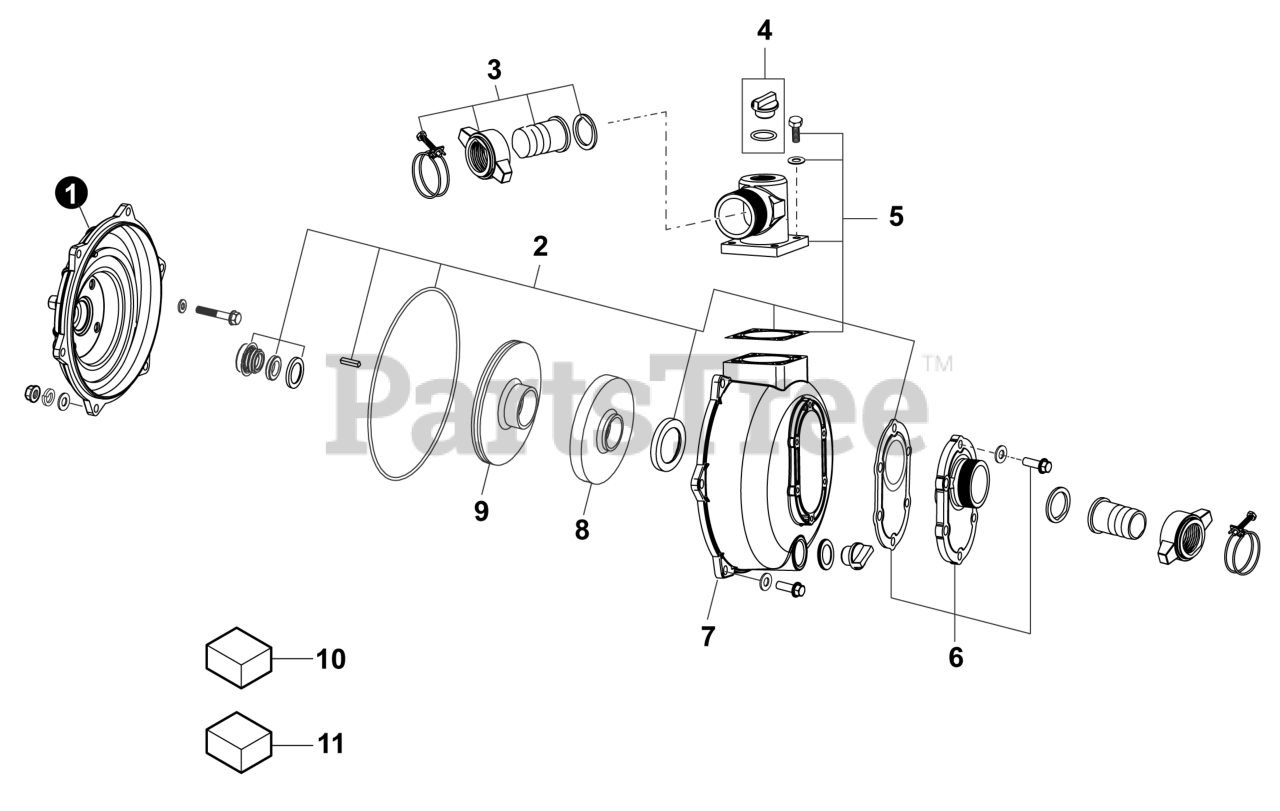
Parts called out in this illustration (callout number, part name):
1	CASING, PUMP
2	KIT, SEAL
3	KIT, HOSE COUPLING
4	ASSY., PUMP PLUG
5	KIT, OUTLET
6	KIT, INLET
7	CASING, FRONT PUMP
8	DIFFUSER
9	IMPELLER
10	KIT, HARDWARE
11	KIT, ENGINE MOUNTING HARDWARE
